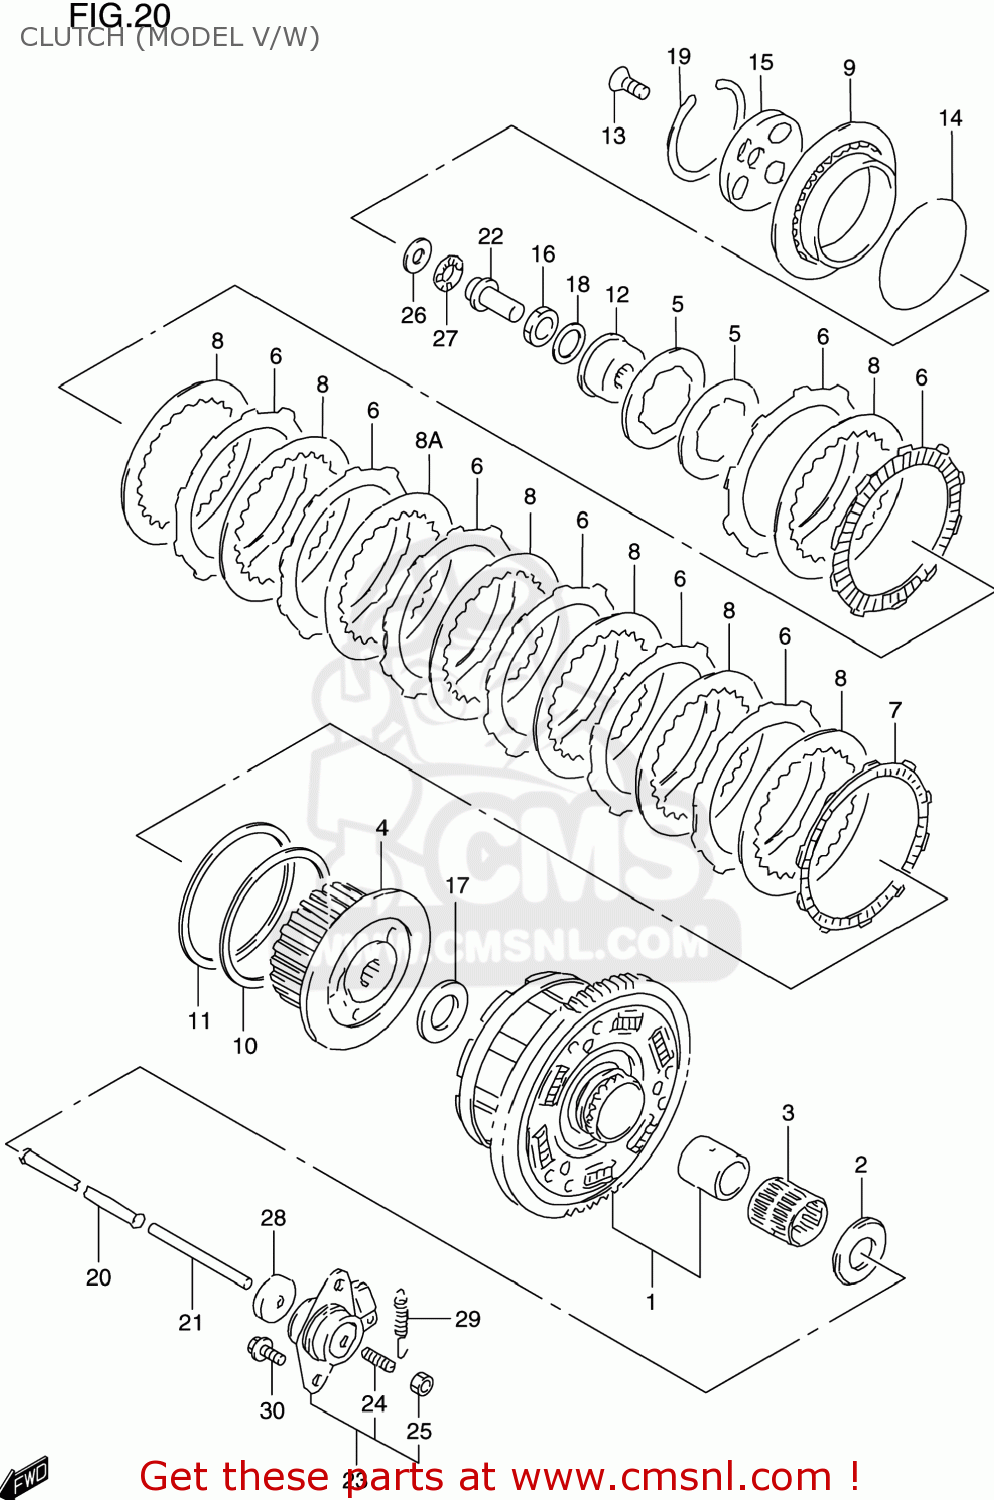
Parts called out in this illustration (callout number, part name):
1	GEAR ASSY,PRI DRIVEN
2	WASHER(25X54X2.5)
3	BEARING(35X40X35.8)
4	HUB,CLUTCH SLEEVE
5	SPRING,CLUTCH
6	PLATE,CLUTCH DRIVE NO (NAS)
7	PLATE,CLUTCH DRIVE
8	PLATE,CLUTCH DRIVEN NO.1
8A	PLATE,CLUTCH DRIVEN NO.2
9	DISC,CLUTCH PRESSURE
10	SEAT,CLUTCH PLATE WAVE WASHER
11	WASHER,CLUTCH PLATE WAVE
12	HOLDER,CLUTCH SPRING
13	SCREW,CLUTCH SPRING HOLDER
14	SEAT,CLUTCH SPRING
15	LIFTER,CLUTCH PRESSURE DISC
16	NUT
17	WASHER
18	WASHER
19	CIRCLIP
20	ROD,CLUTCH
21	ROD,CLUTCH PUSH,L
22	PIECE,CLUTCH PUSH
23	SCREW ASSY,CLUTCH RELEASE
24	SCREW(6X25)
25	NUT
26	WASHER(15.5X28X1)
27	BEARING(15X28X2)
28	SEAL,OIL(6X34X5.5)
29	SPRING
30	BOLT
